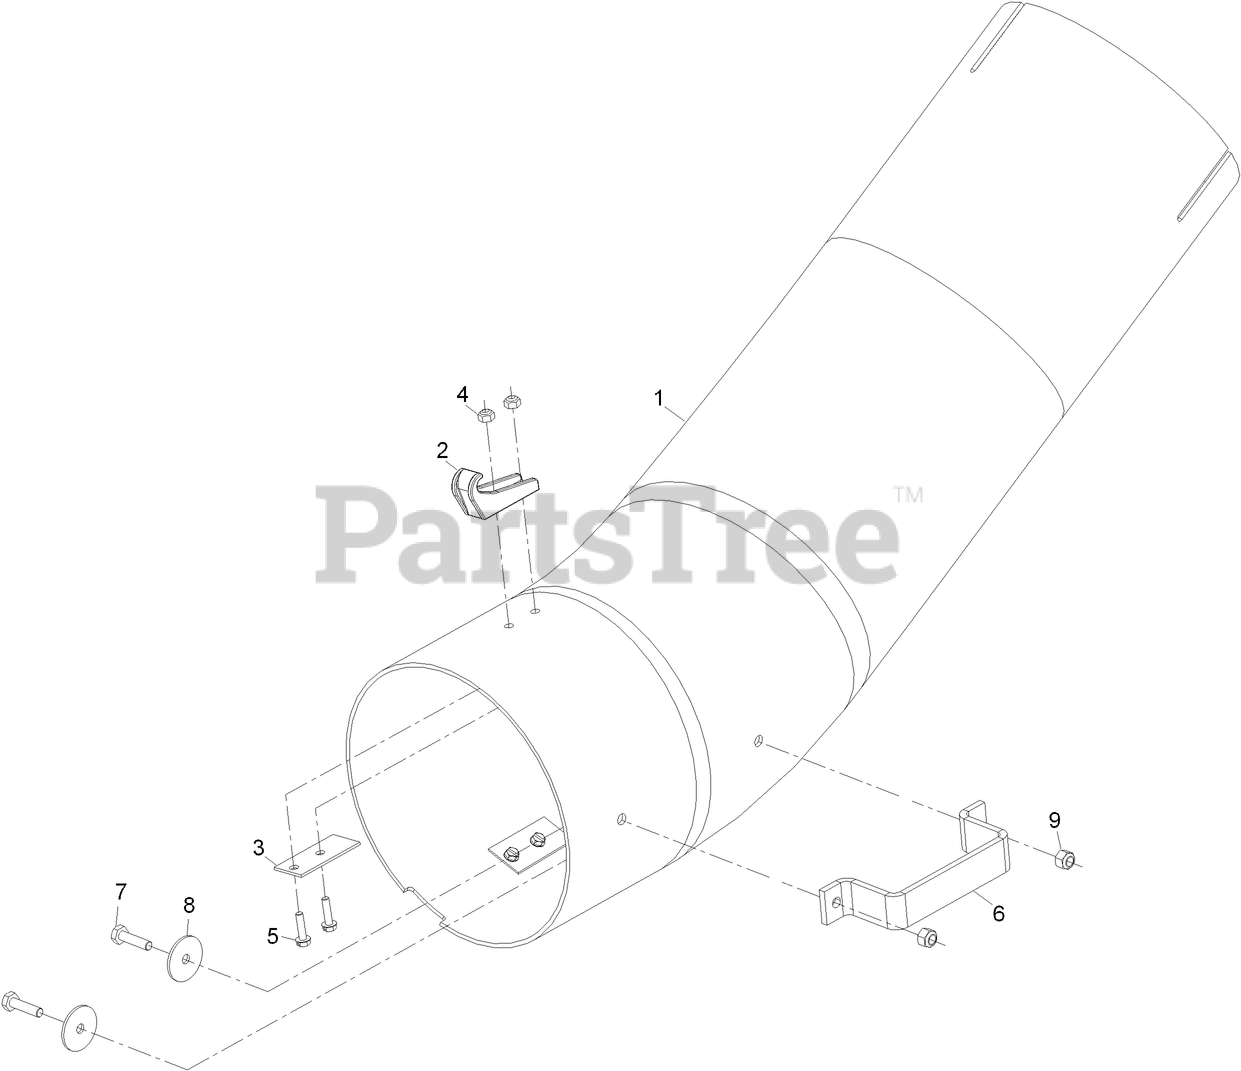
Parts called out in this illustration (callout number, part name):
2	LATCH-CATCH
3	PLATE-BACKING
4	TUBE-LOWER
5	SCREW-HH
6	WASHER-FLAT
7	NUT-LOCK, NI
8	NUT-LOCK, NI
9	SCREW-HWH
